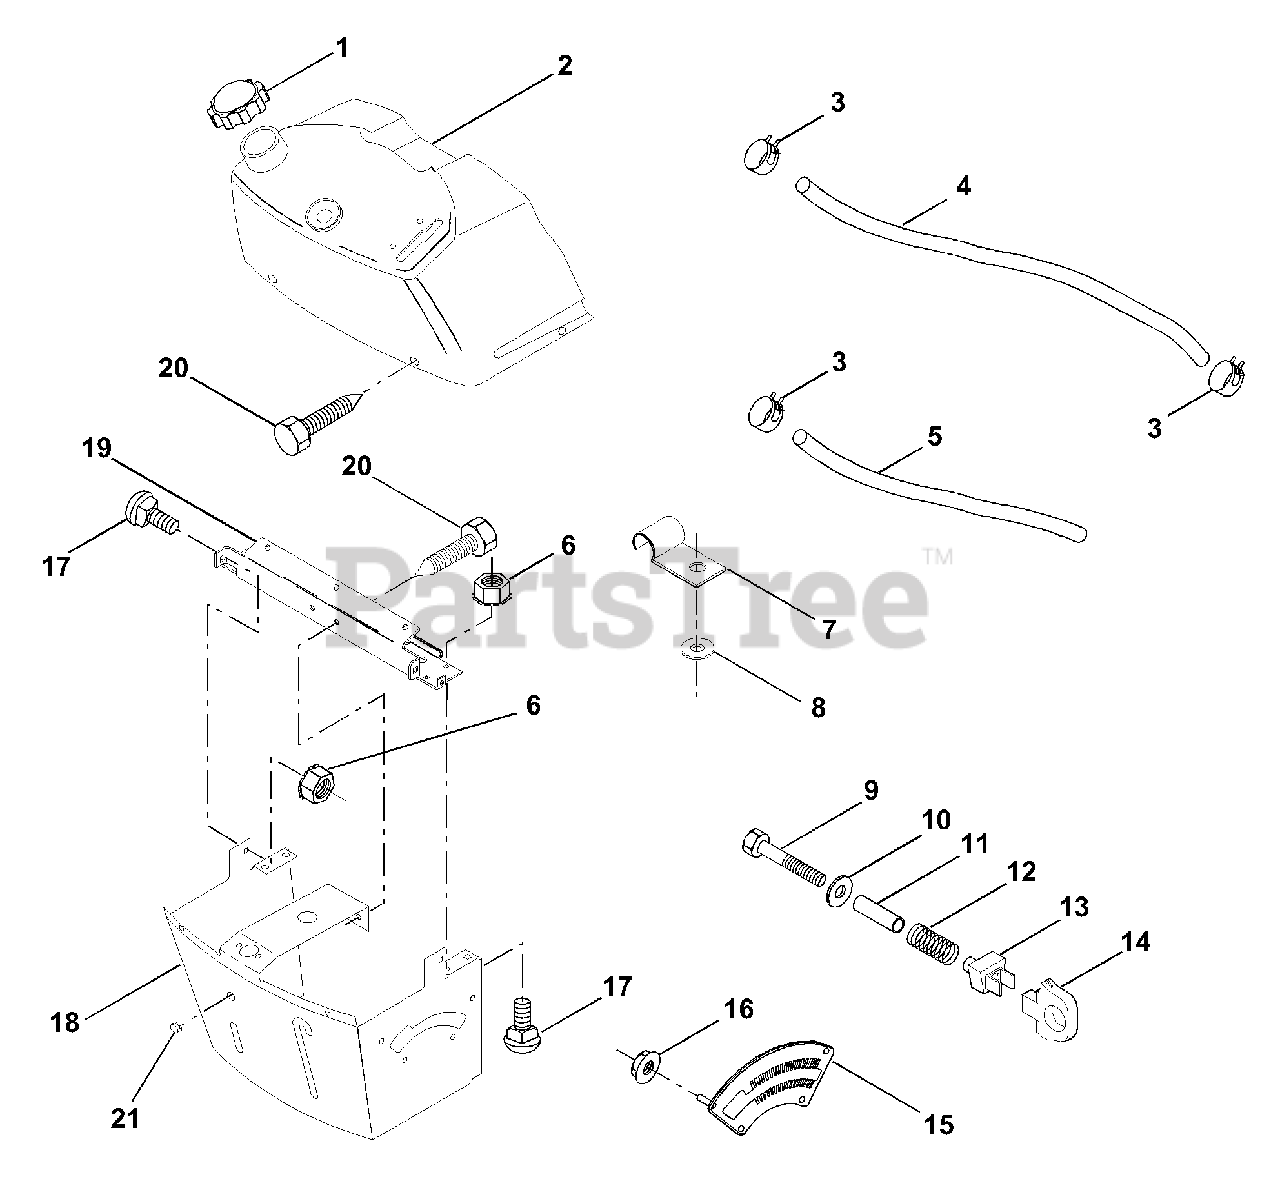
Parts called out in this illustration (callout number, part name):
2	Assembly, Dash & Fuel Tank
3	Clamp, Hose
4	Line, Fuel
5	Line, Fuel
6	Nut, Hex, Keps 1/4-20
7	Clip, Fuel Line
8	Washer 9/32 x 3/4 x 16 Ga.
9	Bolt, Hex, Fin 1/4-20 x 1-3/4
10	Washer 11/32 x 11/16 x 16 Ga.
11	Spacer, Split
13	Clip, Height Adjustment
14	Knob, Height Stop
15	Adjustment, Quadrant Height
16	Nut, Self-Threading 3/16-18
17	Bolt, Carriage 1/4-20 x 1/2 Gr. 5
18	Support Assembly, Dash
19	Brace, Cross
20	Screw, Self-Tapping 1/4-20 x 1/2
21	Plug Dome Black
